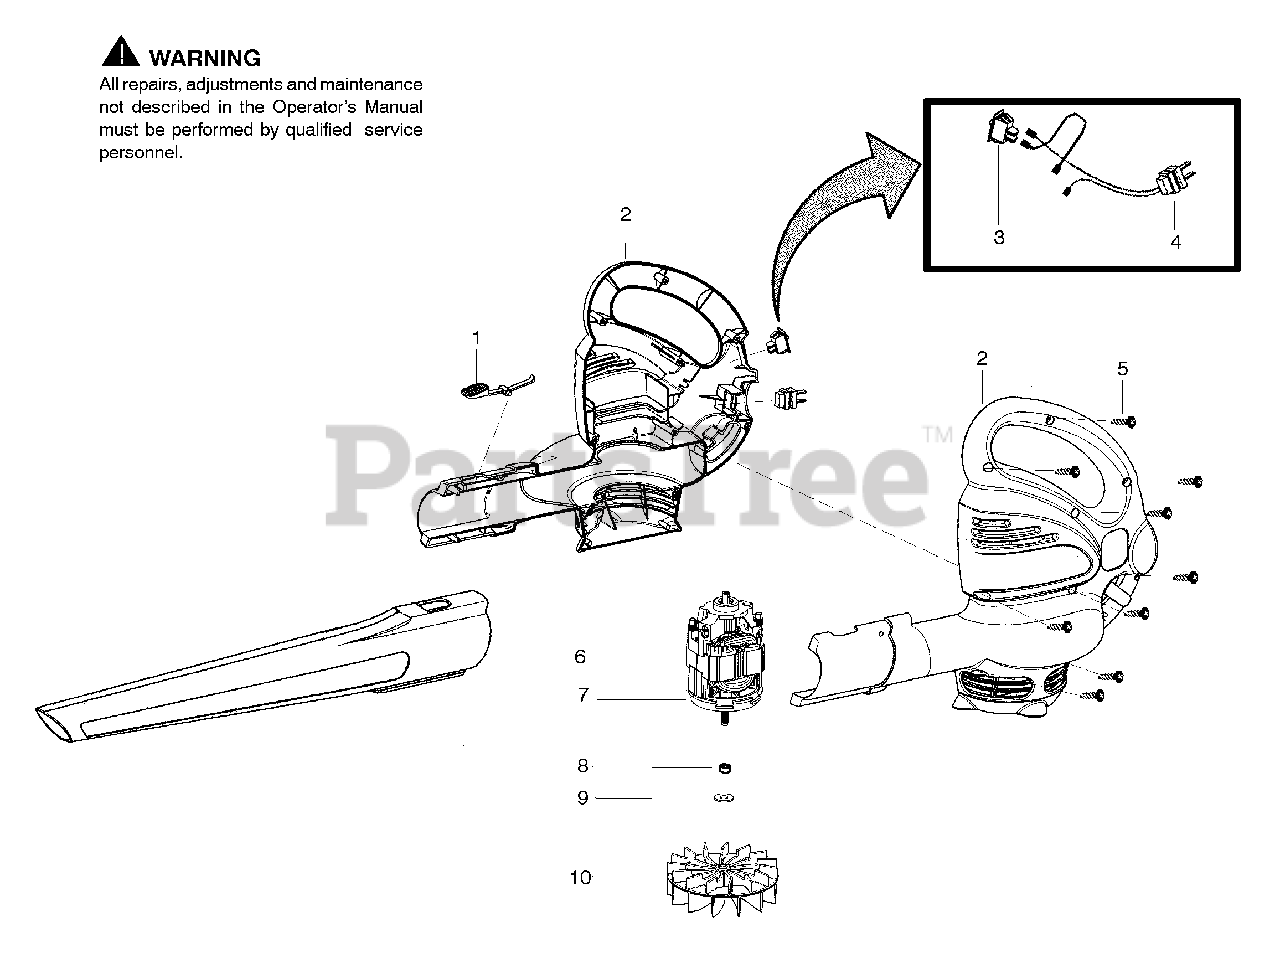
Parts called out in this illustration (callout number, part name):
1	Button - Tube Latch
2	Housing Set
3	Switch - on/off
4	Assy. Wiring Harness
6	Tube - Blower
7	Assy. Motor
10	Impeller
